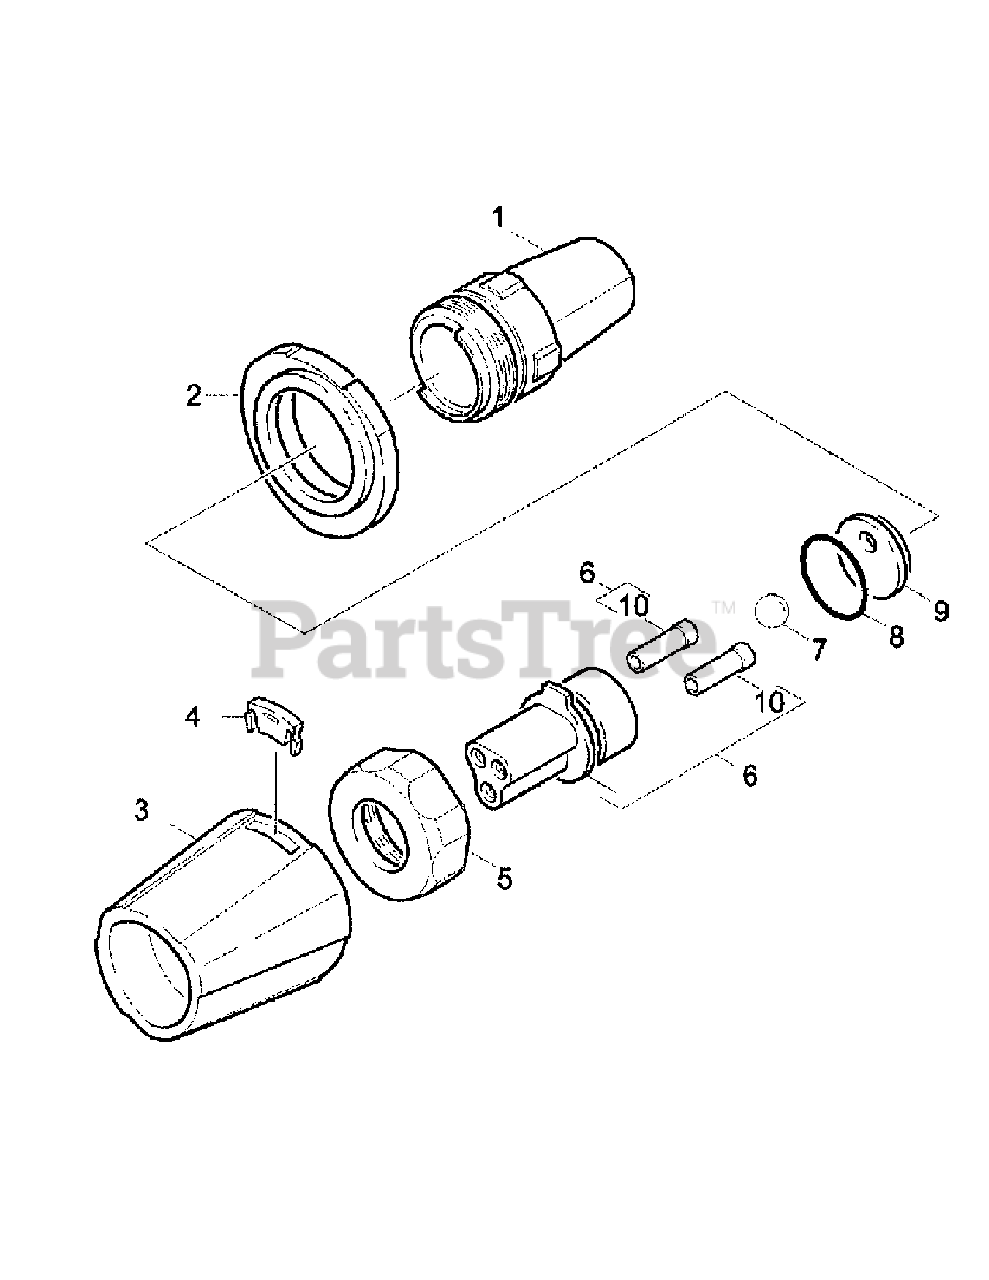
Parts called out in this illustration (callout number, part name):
1	Housing
2	Ring
3	Housing
4	Retainer Clip
5	Union Nut
6	Nozzle Holder
7	Ball
8	O-Ring
9	Disc
10	Rectifier
